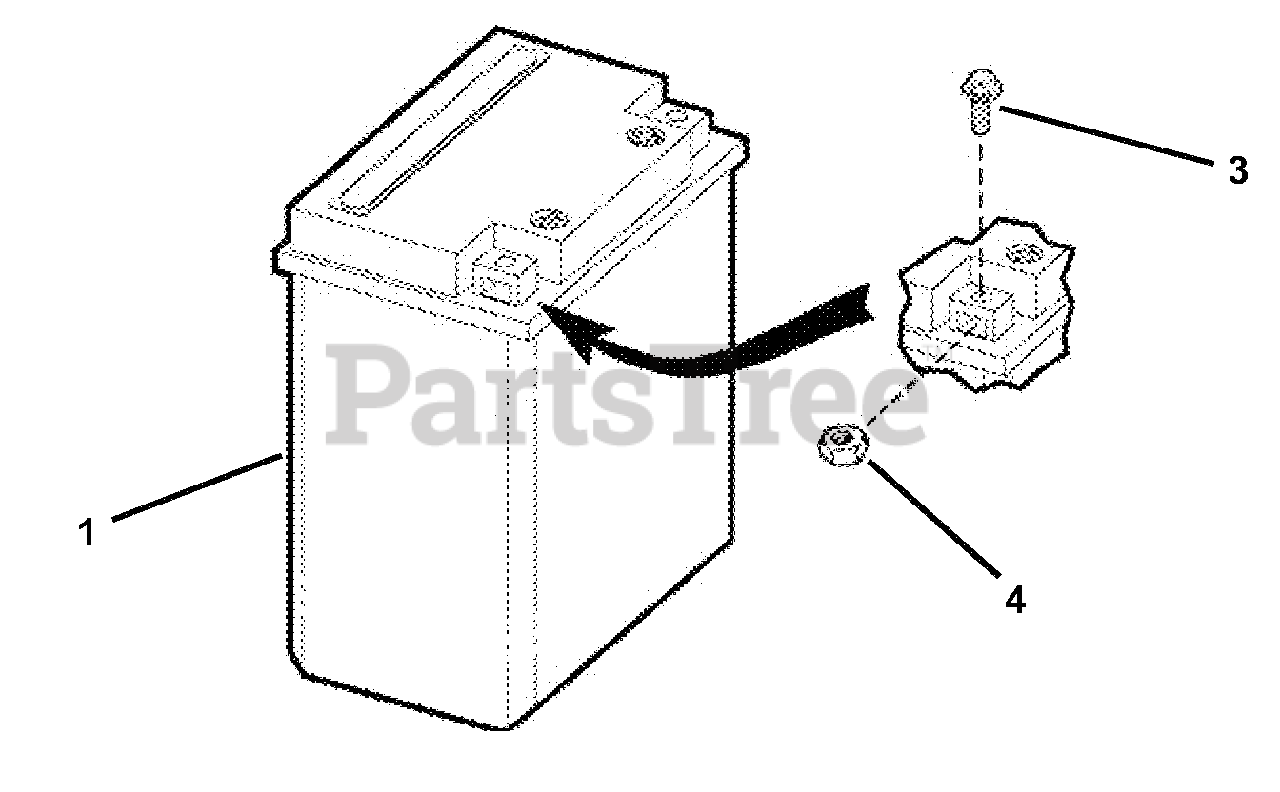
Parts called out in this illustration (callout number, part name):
1	BATTERY, 12V, 3 Amp, Type YMF-14L-2 (Yuasa P/N M321G)
3	SCREW, 1/4-20 x 3/8" Hex Washer Self-Tap
4	NUT, 1/4-20 Hex, Grade 5
